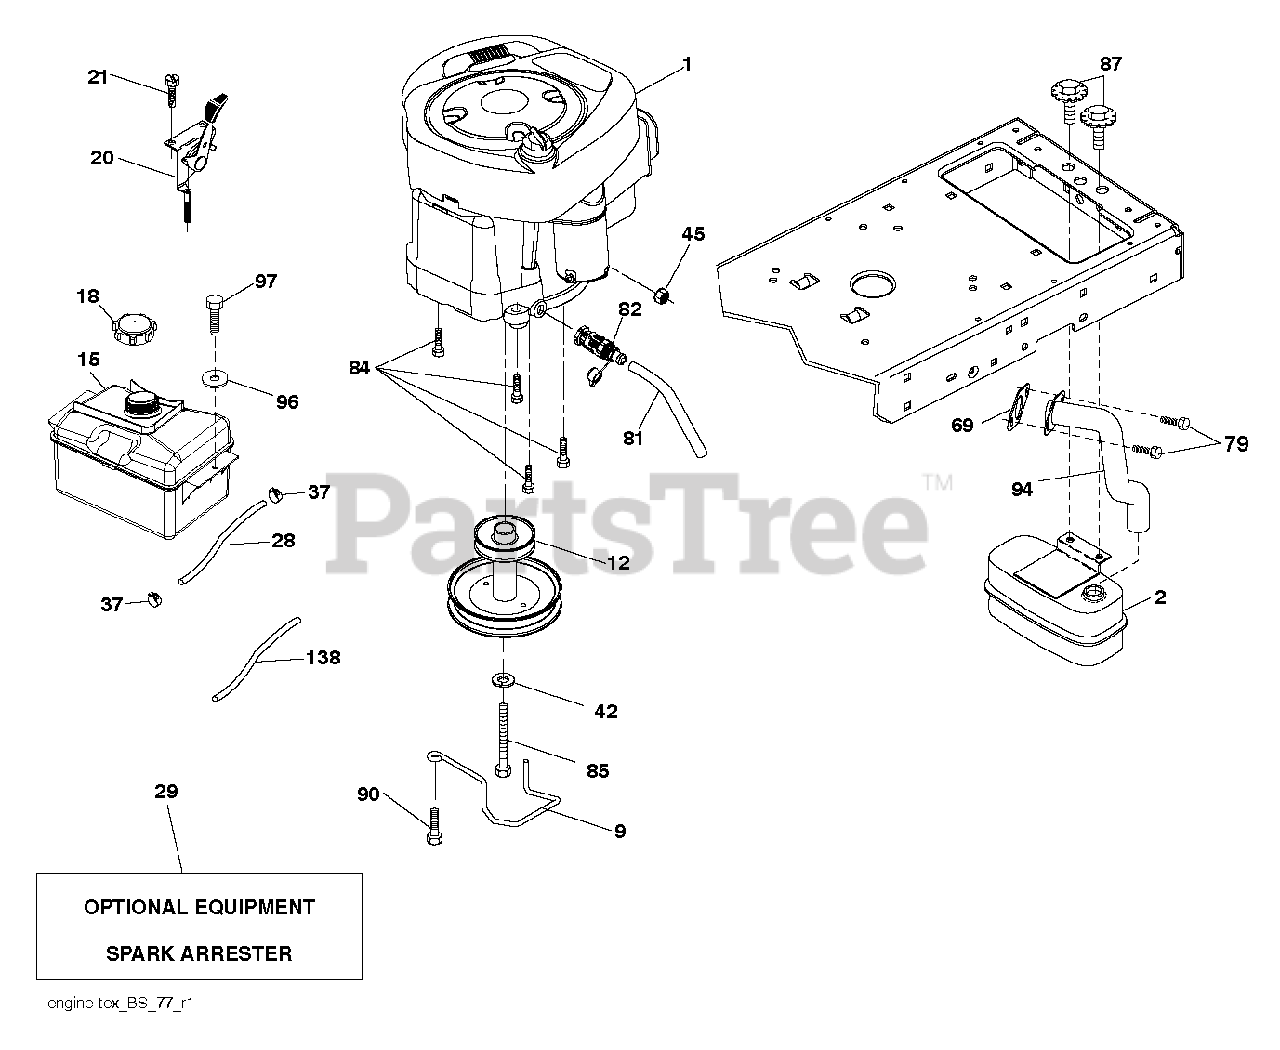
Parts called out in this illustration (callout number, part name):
2	MUFFLER.ASM.SNGL.XTNDED.DFLCTR
9	KEEPER.BELT.ENGINE
12	PULLEY.ENGINE
15	TANK.ASM.FRT.2.5 GAL.W/CAP.EPA
18	CAP.FUEL.2 WAY VENT
20	CONTROL.TH/CK.C.
21	SCREW.#10 X 0.750.BOS
28	LINE.FUEL.20"FRONT.EMI
29	KIT.SPARK ARRESTOR 794945 B&S
37	HOSE CLAMP
42	LOCKWASHER
45	NUT
69	REPL BY 532 27 22-93
79	SCREW.SOCKET HD.5/16-1
81	TUBE, DRAIN OIL ASM.
82	VALUE.OIL.DRAIN
84	SCREW.3/8-16
85	BOLT HEX 7/16-20X4-1/4"
87	BOLT, 5/16-18 X 1 3/4
90	SCREW 3/8-16X1
94	EXHAUST.TUBE.B&S.28/31
97	SCREW HEXWSHR 1/4-20X3/4
138	RP PURGE LINE
